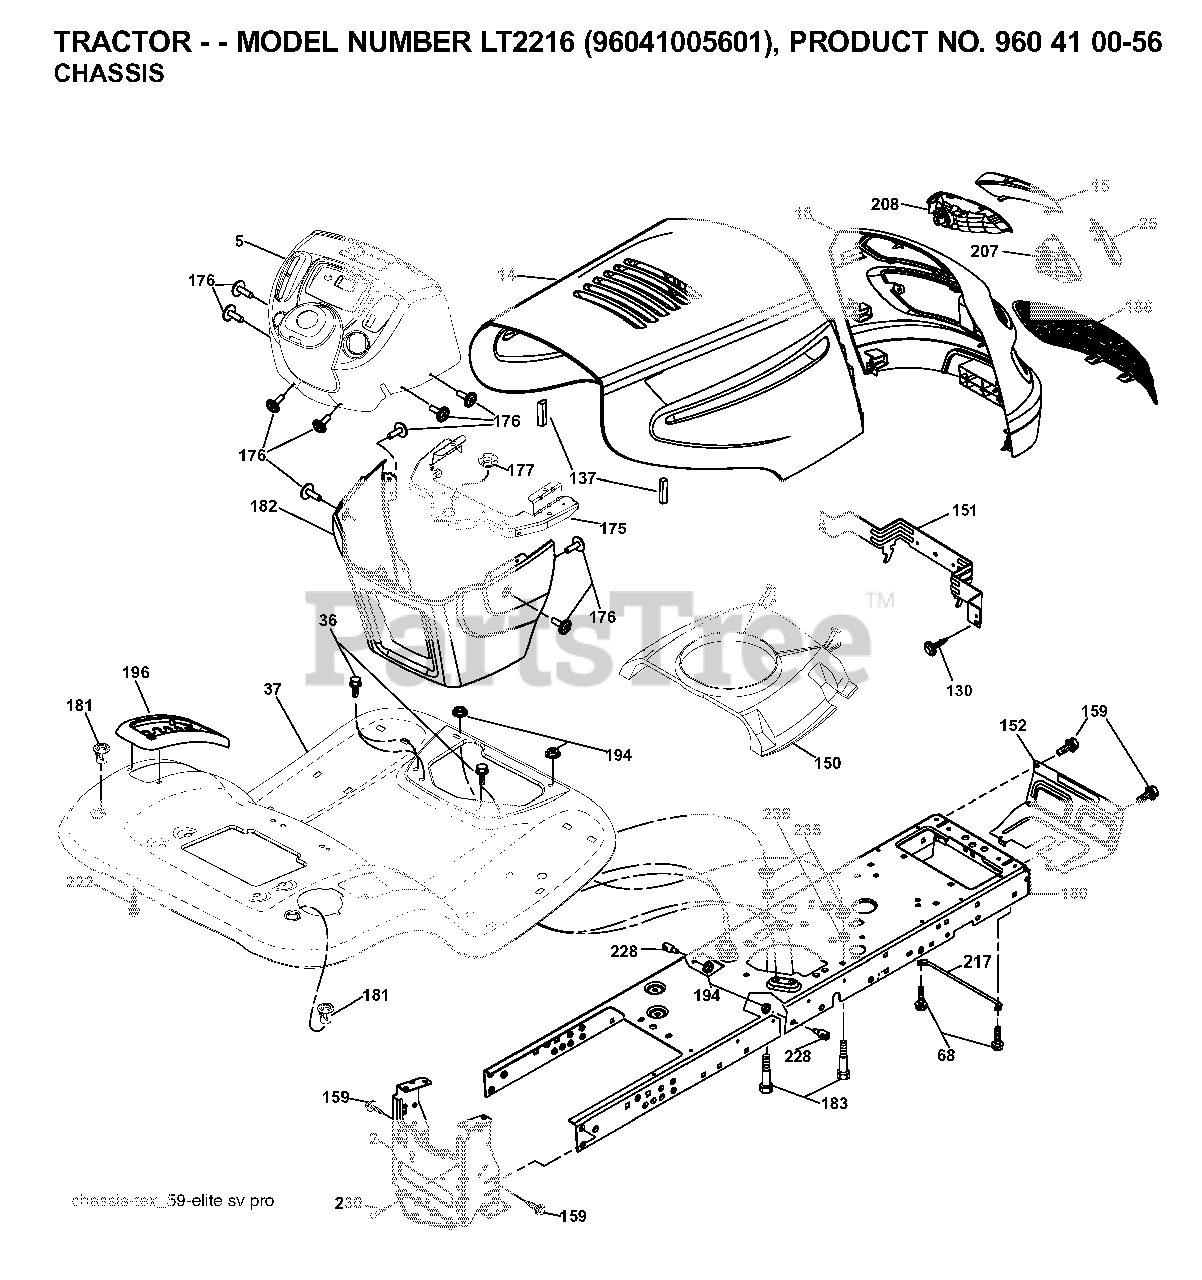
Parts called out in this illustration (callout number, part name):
2	DRAWBAR.1PC.NSTL
5	DASH.P/L.TEX.CBL.CL.N/CHK.BLAC
36	SCREW 5/16"
130	SCREW
137	BUMPER.HOOD.LARGE.1.75"
151	BRACKET PIVOT
152	SHIELD.BROWNING/DEBRIS
159	SCREW
175	CROSSMEMBER.LT
176	SCREW.#10-24X5/8.RN.QU
177	BUSHING STEERING
180	CHASSIS.STAMPING.LT/GT
181	FEND/FTRST.PCH.CPH.NFW
182	DASH.LOWER.LT.CCS
183	BOLT.5/16-18X1-1/4 FULL.THREAD
194	NUT LOCK HEX FLANGE 5/16-18
196	CONSOLE.ASM.DECK.LIFT.TLT.BLAC
207	BEZEL GRILL RH
208	BEZEL GRILL LH
217	ROD.PIVOT.HOOD
222	SCREW.1/4-20X5/8
228	STUD.FASTNER.W/ANTI-ROTATE
230	SHOULDER BOLT 5/16-18TT
235	SPACER FENDER
236	NUT.CENTERLOCK.5/16-
